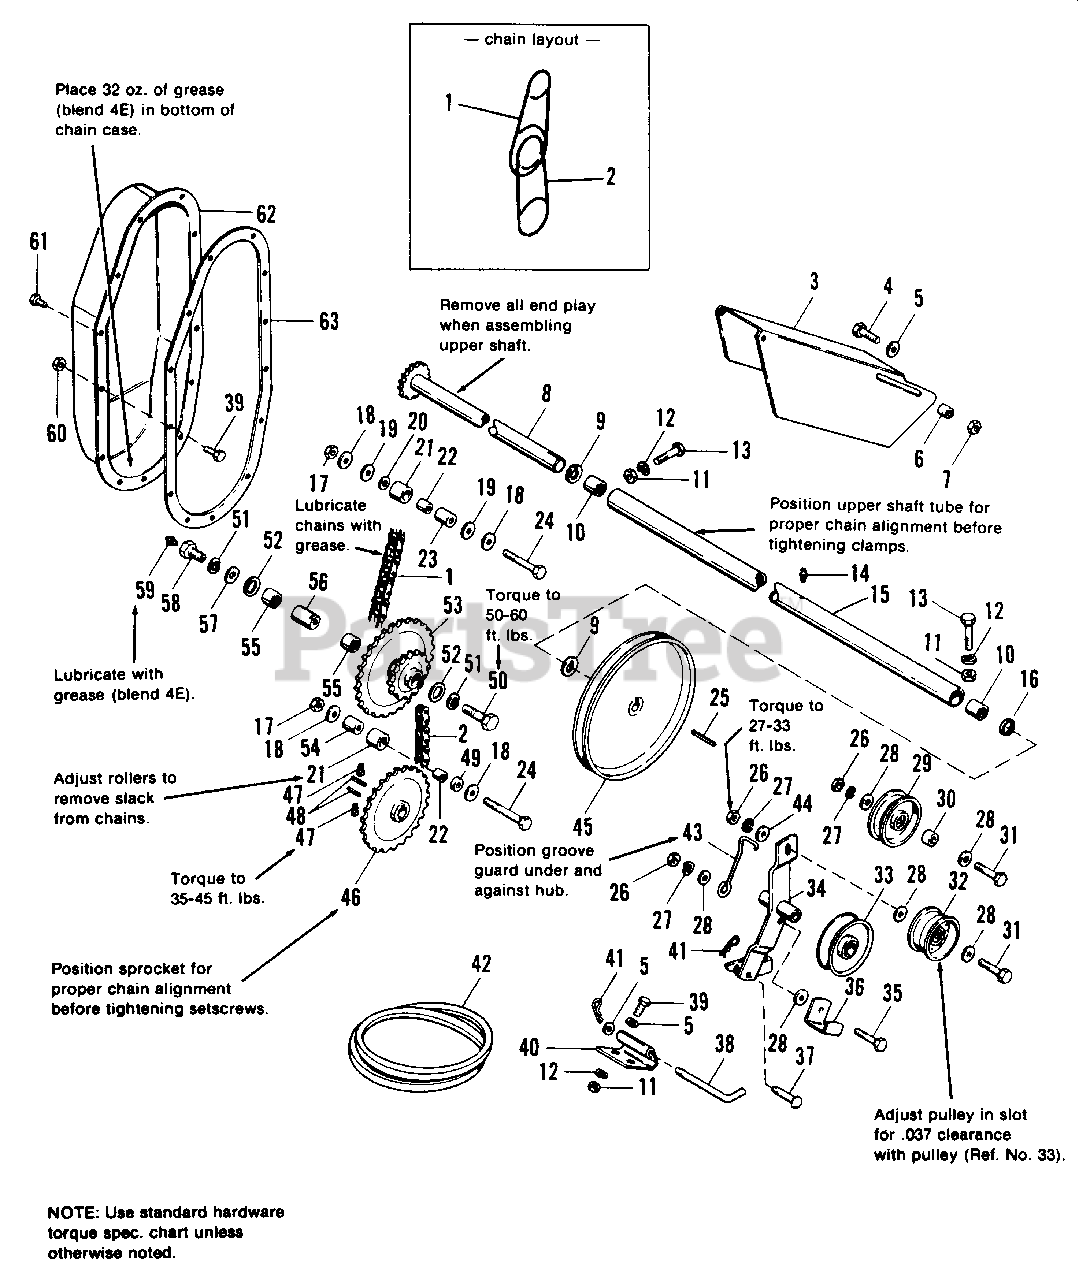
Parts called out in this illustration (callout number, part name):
1	CHAIN, Roller
2	CHAIN, Roller
3	GUARD, Belt
4	CAPSCREW, Hex Hd., 1/4-20 x 1
5	WASHER, Plain, 1/4
7	LOCKNUT, Hex, 1/4-20
8	SHAFT ASSY.
10	BEARING, Needle
11	NUT, Hex, Full, 5/16-18
12	LOCKWASHER, 5/16
13	CAPSCREW, Hex, 5/16-18 x 1-1/2
14	FITTING, Grease
15	HOUSING ASSY.
17	LOCKNUT, Hex, 3/8-16
18	WASHER, Special
20	WASHER, Special
24	CAPSCREW, Hex Hd., 3/8-16 x 4
25	KEY
26	NUT, Hex, Full, 3/8-16
27	LOCKWASHER, 3/8
28	WASHER, 5/16
29	PULLEY, Idler
31	CAPSCREW, Hex Hd., 3/8-16 x 1-1/2
32	PULLEY ASSY., Idler
34	ARM ASSY., Idler
35	CAPSCREW, Hex Hd., 3/8-16 x 1-1/4
36	GUARD, Belt
39	CAPSCREW, Hex Hd., 5/16-18 x 5/8
40	BRACKET, Guard Pivot
41	CLIP, Spring
42	BELT, "V", Drive
43	GUARD, Groove
46	SPROCKET ASSY.
47	SETSCREW, Sq. Hd., 3/8-16 x 3/4
50	CAPSCREW, Hex Hd., 1/2-20 x 1
51	LOCKWASHER, 1/2
53	SPROCKET ASSY.
57	WASHER, 1/2
58	BOLT, Side, R.H.
59	FITTING, Grease
60	LOCKNUT, Hex, 5/16-18
61	SCREW, Hex Hd., 5/16-18 x 1/2
62	COVER ASSY.
